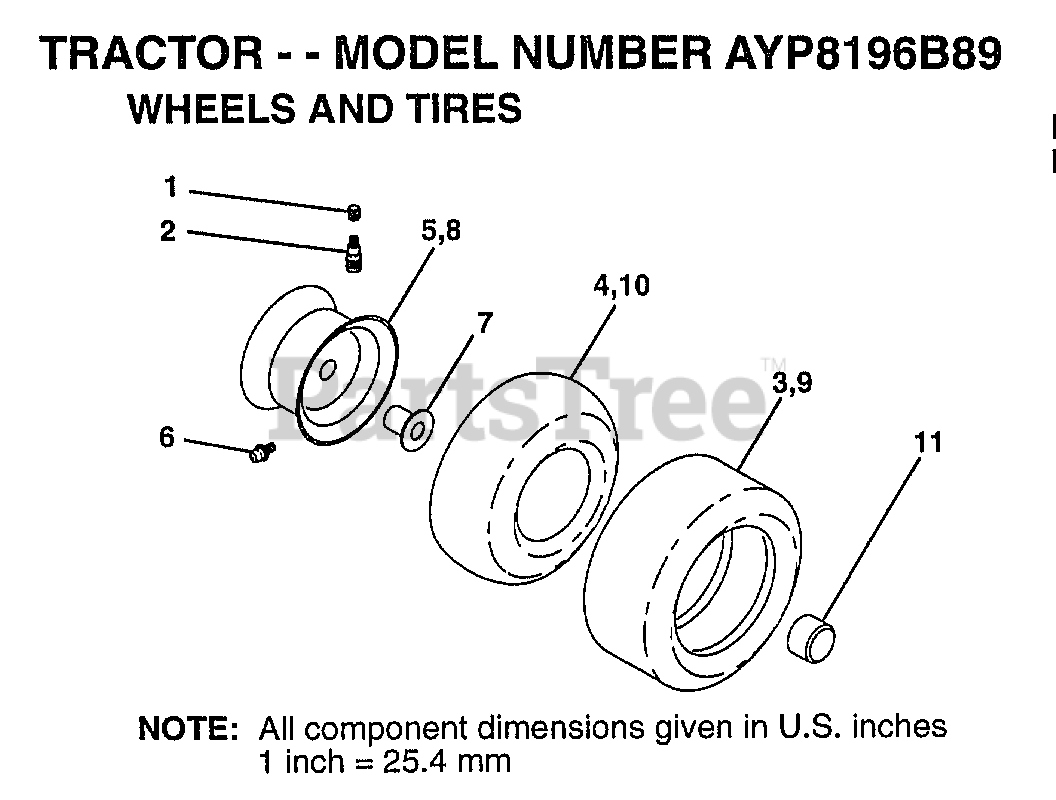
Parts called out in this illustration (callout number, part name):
1	VALVE CAP
2	VALVE STEM LT
4	TUBE.5.3/4.5/6
5	"RIM ASM 8"" FRT"
6	FITTING LT
7	"FLANGE, BEARING"
8	RIM.REAR.
10	TUBE.23X8/10-12
11	HUB CAP
